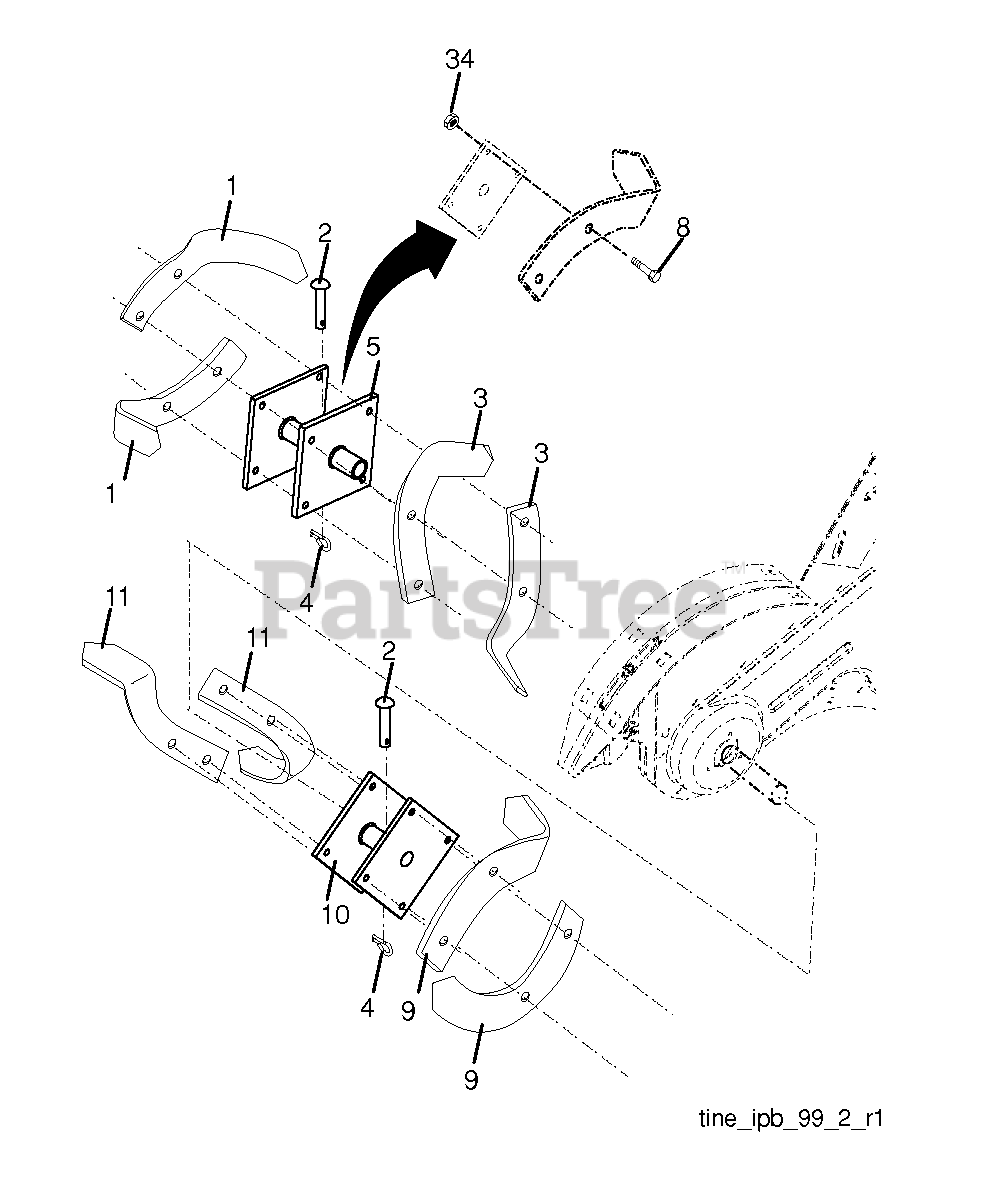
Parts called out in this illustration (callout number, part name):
2	CLEVIS PIN
3	TINE.LH.12"
5	HUB.&.PLATE.LH.TILLER.BLACK
8	BOLT.HEX.001X20.37-24X1.ZINC
11	TINE.RH.12"(72R)
34	NUT CROWNLOCK 3/8-24
